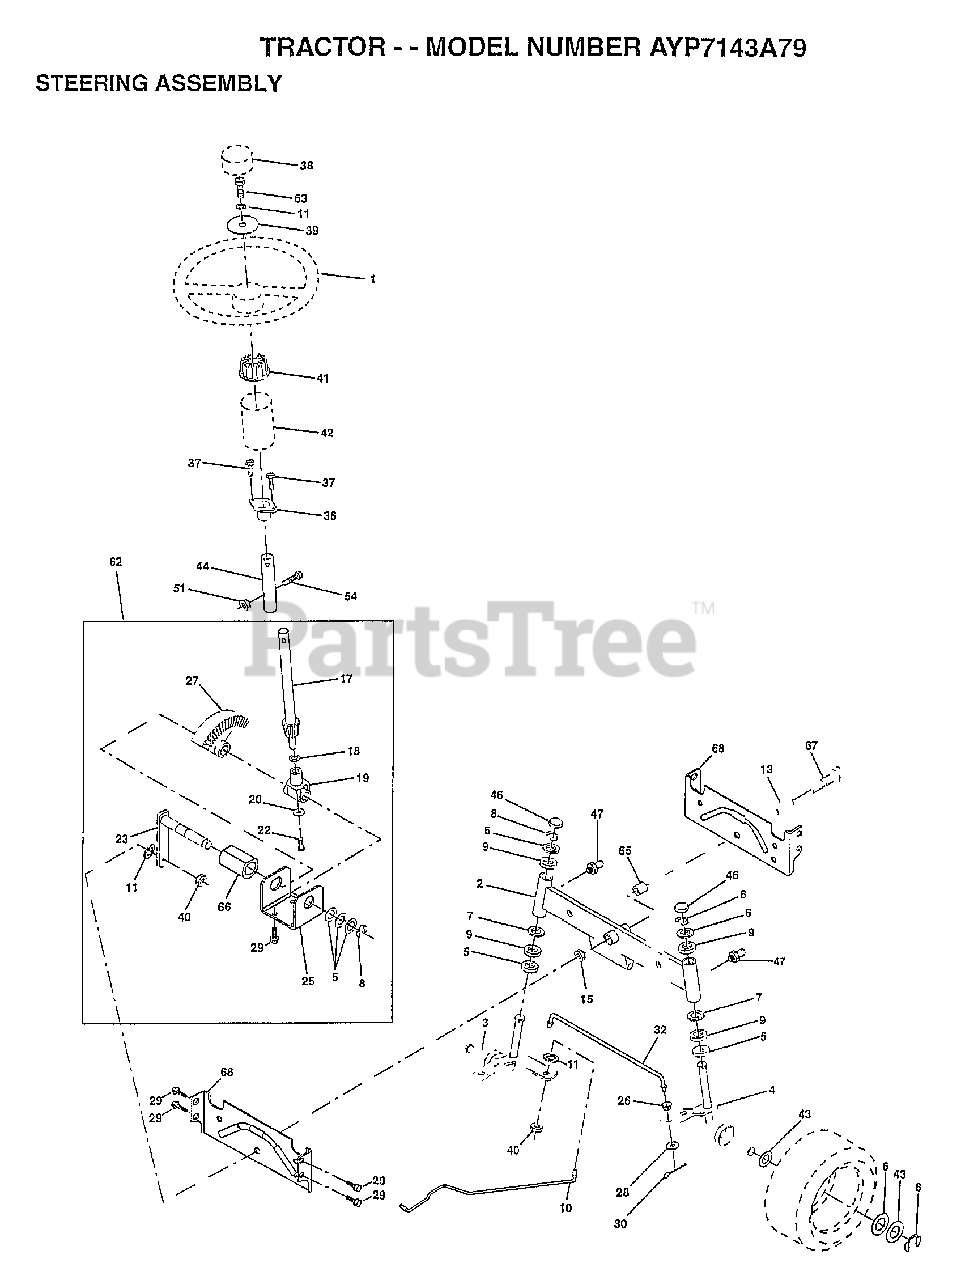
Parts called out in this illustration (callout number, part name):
1	CHASSIS ASM
3	SCREW
4	WASHER
5	BUMPER-HOOD/DASH
6	SADDLE-SILKSCREEN
8	"CLIP,INSULATOR"
9	DASH.SILKSCREENED
11	"PANEL-DASH,LH"
12	CLIP.TINNERMAN
14	SCREW LT
15	SCREW
24	BOLT
25	WASHER
26	NUT
28	GRILLE-MS428
29	LENS GRILLE
30	FENDER
31	BRKT FENDER
33	FOOTREST LH
34	FOOTREST RH
35	BOLT
38	BRACKET ASM LH
39	BRACKET ASM RH
51	NUT
52	WASHER
53	BRACKET.GRILLE.LH
55	BRACKET.GRILLE.RH
58	AIR DUCT
140	BRKT SUSPENSION
145	"ROD POVOT,CHASSIS"
147	BOLT LT
